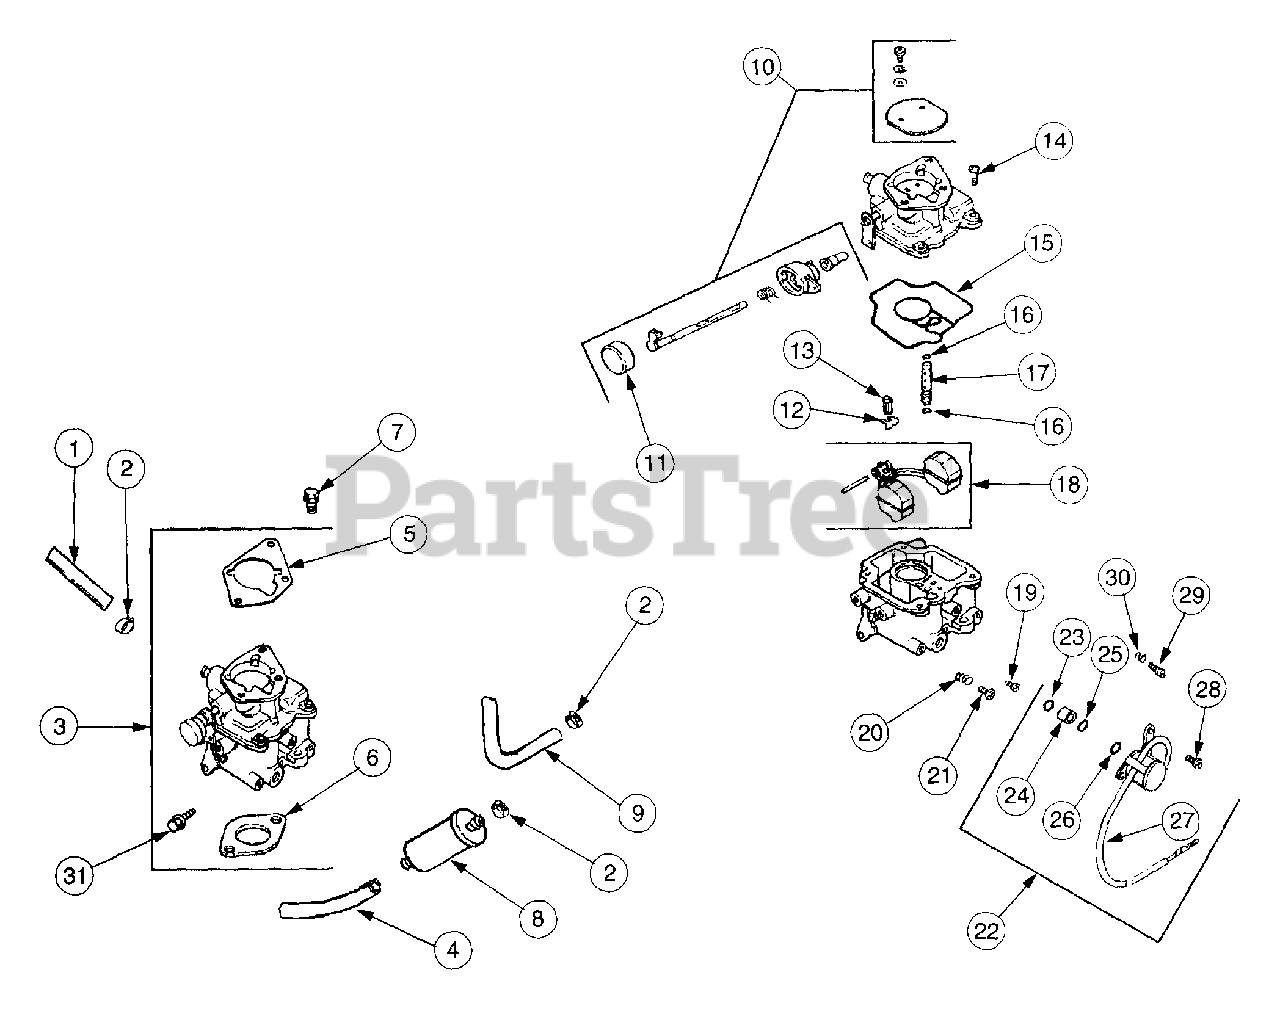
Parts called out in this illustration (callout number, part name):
1	Line, Fuel 10"
2	Clamp, Hose
3	Kit, Carb
4	Insulation, Fuel Line
5	Gasket, Air Cleaner Base
6	Gasket, Carburetor
7	Screw, Hex Flange M6 x 1.0 x 30
8	Filter, Fuel
9	Line, Fuel 11"
10	Kit, Choke Repair
11	Cap, Choke Lever
12	Clip, Inlet Needle Valve
13	Valve, Inlet Needle
14	Screw, Carburetor Body
15	Gasket, Carburetor
16	O-Ring, Slow Jet
18	Kit, Float Repair
20	Spring, Idle Adjust Screw
21	Screw, Idle Adjusting
22	Kit, Solenoid
24	Seat, Solenoid
27	Solenoid
28	Screw, Solenoid
29	Needle, Idle
30	Spring, Idle Needle
31	Screw, Throttle Stop
